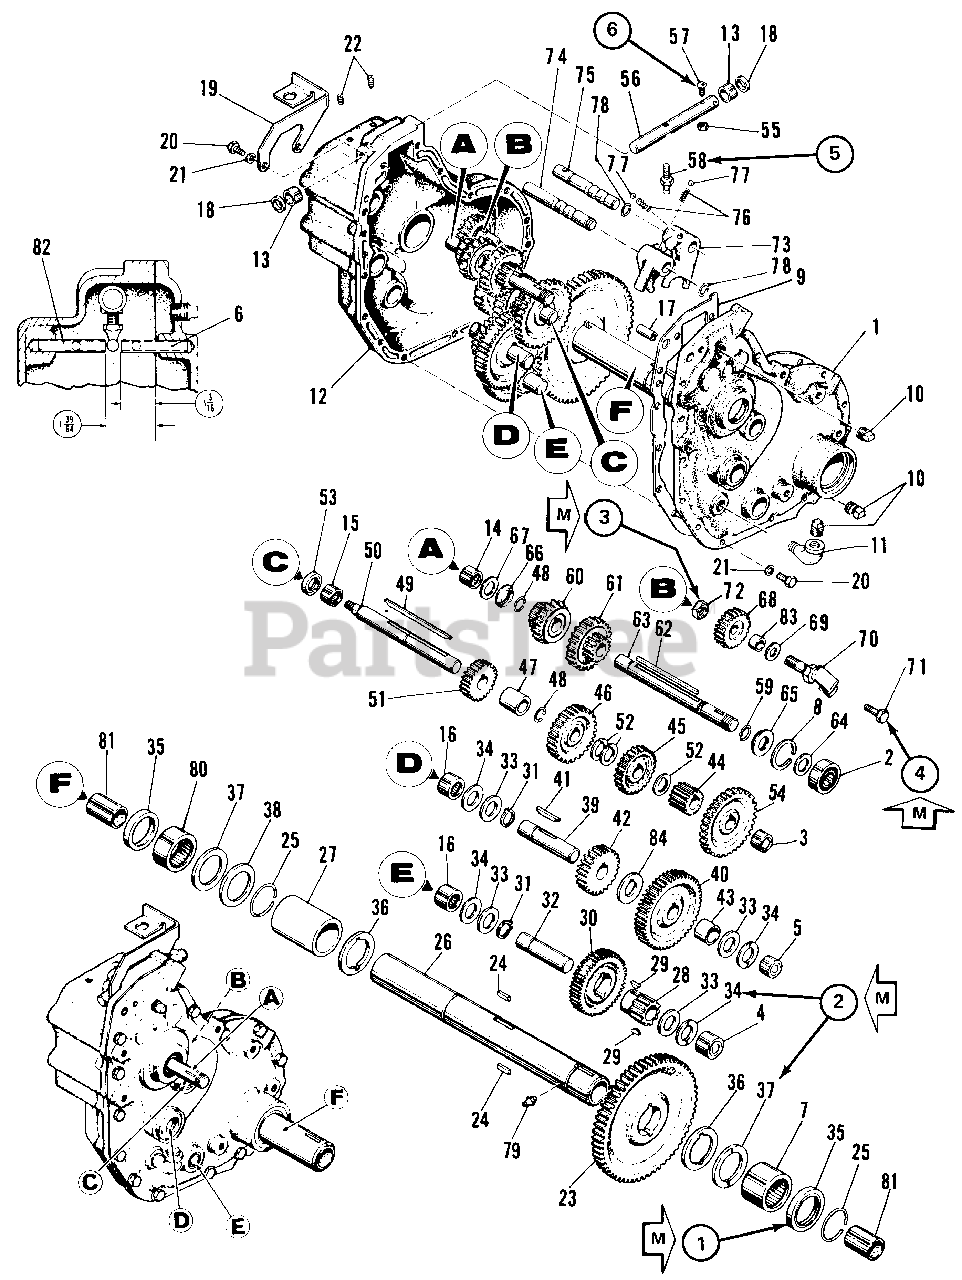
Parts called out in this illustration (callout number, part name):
1	COVER, Gear Case
2	BEARING, Ball
3	BEARING, Needle
4	BEARING, Needle
5	BEARING, Needle
6	ROLL PIN ASSEMBLY
7	BEARING, Needle
8	RING, Retaining
9	GASKET, Gear Case
10	PLUG, Pipe, Sq. Hd., 3/8
11	ELBOW, Street
12	GEAR CASE ASSEMBLY
13	SPACER, Diff.
14	BEARING, Needle
15	BEARING, Needle
16	BEARING, Needle
17	PIN, Spring, 3/8 x 1
19	SUPPORT, Switch
20	CAPSCREW, Hex Hd., 5/16-18 x 1
21	LOCKWASHER, 5/16
22	SETSCREW, Soc. Hd., 5/16-18 x 1/2
23	GEAR, Drive
26	TUBE & BUSHING ASSEMBLY
27	SPACER, Axle Tube
28	PINION, 3rd Interm.
29	KEY, Woodruff, No. 6
30	GEAR, 3rd Interm.
31	RING, Retaining
32	SHAFT, 3rd Interm.
36	WASHER, Axle Tube
37	WASHER, Axle Tube
38	WASHER, Axle Tube
39	SHAFT, 2nd Interm.
40	GEAR, 2nd Interm.
42	PINION, 2nd Interm.
44	PINION, 1st Interm.
45	PINION, Driver III
46	GEAR, Driver II
48	RING, Retaining
50	SHAFT, 1st Interm.
51	PINION, Rev. & IV
54	GEAR, Driven I
55	NUT, Jam Hex, 5/16-18
56	ROD, Shift
57	BOLT CARRIAGE, Special
58	STEM, Shift
59	RING, Retaining
60	PINION ASSEMBLY REV. & II
61	PINION ASSEMBLY I & II
63	SHAFT, Pulley
70	REV. GEAR PIN ASSEMBLY
71	CAPSCREW, Hex Hd., 3/8-16 x 1-1/4
72	LOCKNUT, Hex, 1/2-20
73	FORK, Shift
74	SHAFT, Shifter
75	SHAFT, Shifter, Hi-Lo
77	BALL, Shiftlock
78	RING, Retaining
79	FITTING, Grease
80	BEARING, Needle
82	ROLL PIN ASSY
83	SPACER, Rev. Gear
